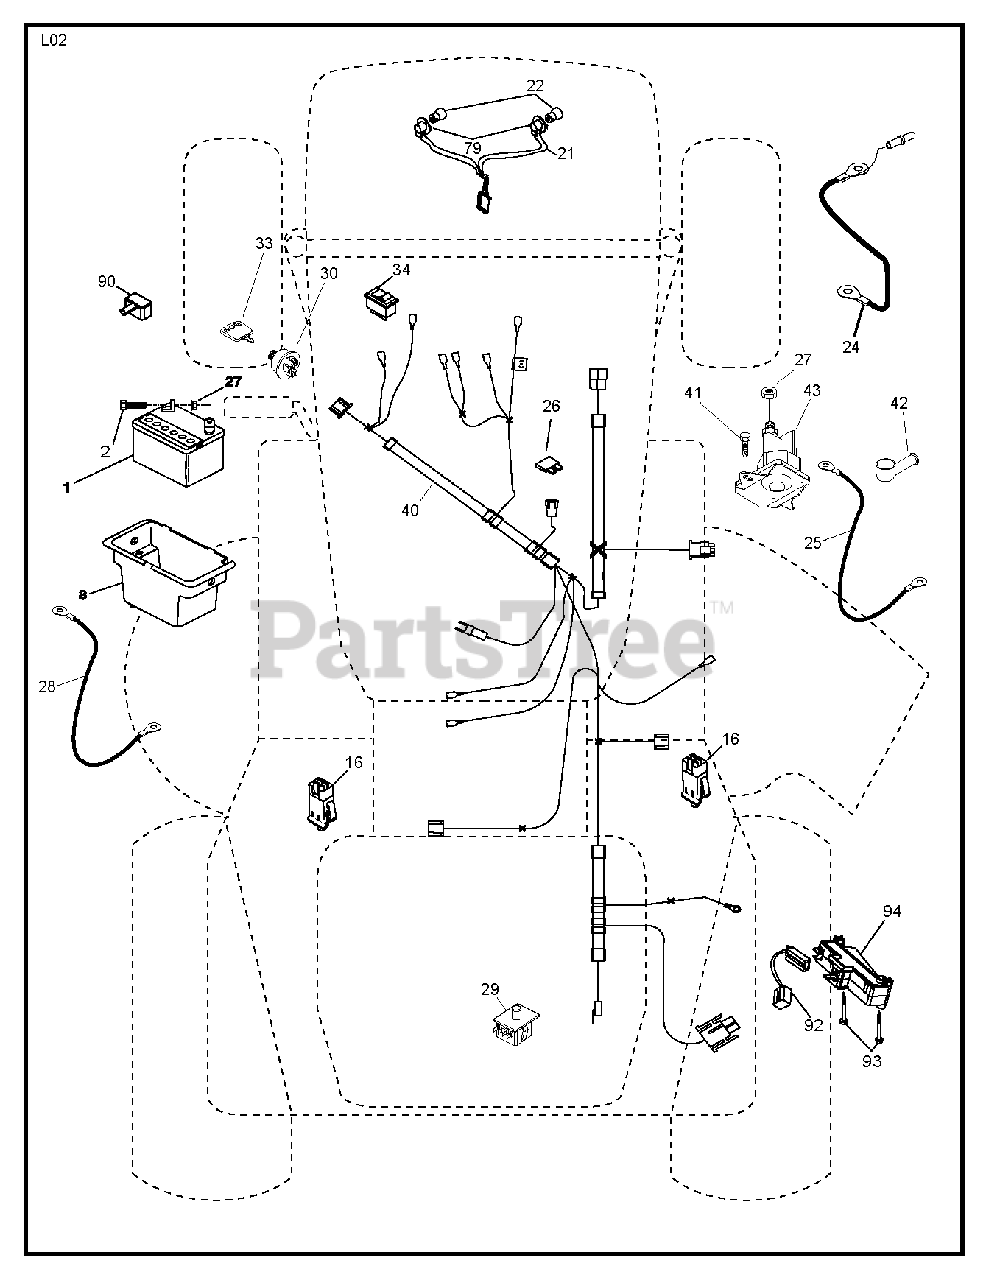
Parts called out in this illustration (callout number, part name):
1	REPL BY 532 12 38-99
8	BOX.BATTERY.FENDER
16	SWITCH INTERLOOK PUSH-IN
21	HARNESS.W/LIGHT SOCKET
24	CABLE.GROUND.REAR.BTRY.8GA.44"
25	CABLE BATTERY 6 GA. 11" RED
27	NUT
28	CABLE GROUND 6 GA. 12" BLACK
29	SWITCH.SEAT.DP W/RAMPS
30	SWITCH.IGN.DELTA.W.LGH.ROS
33	KEY.CHAIN.BLISTER.PACK.GEN.INT
40	HARNESS.IGN.CABLE.REG.
41	Hex Capscrew, 1/4-20
42	TERMINAL COVER
43	SOLENOID.W/BRASS.PLUNG
79	BULB HOLDER ASM.
90	COVER.TERMINAL.BATTERY
92	HARNESS.PIGTAIL.CONSLE
93	SCREW.PLASTITE
94	MODULE.REVERSE.ROS
